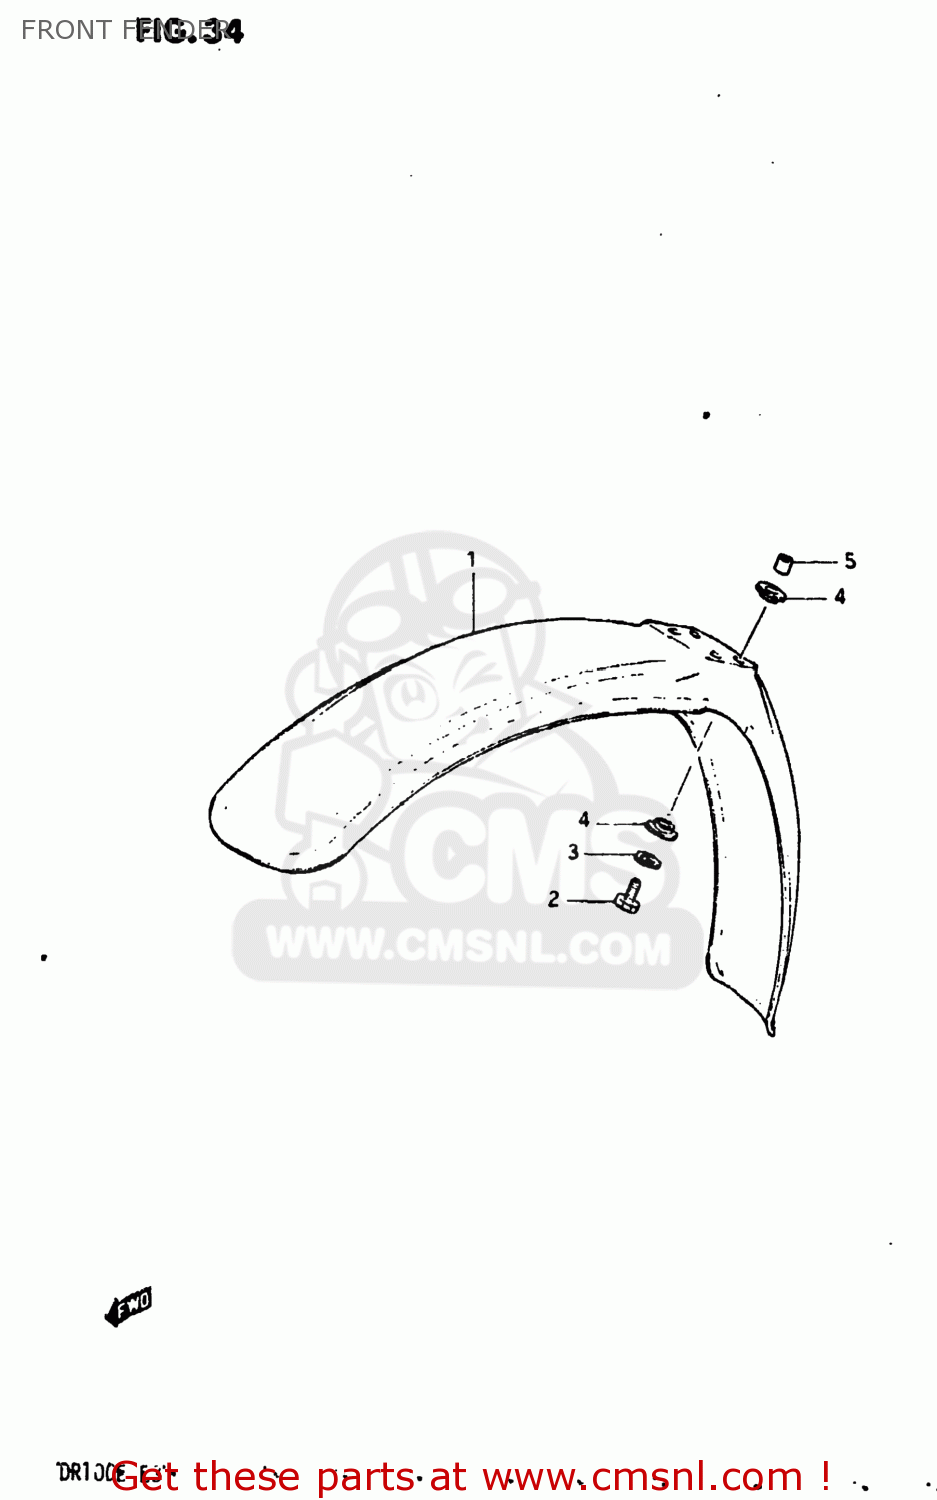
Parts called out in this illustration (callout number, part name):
1	FENDER,FRONT
2	BOLT
3	LOCK WASHER
4	SPACER
5	SPACER (6.8X10X10)
